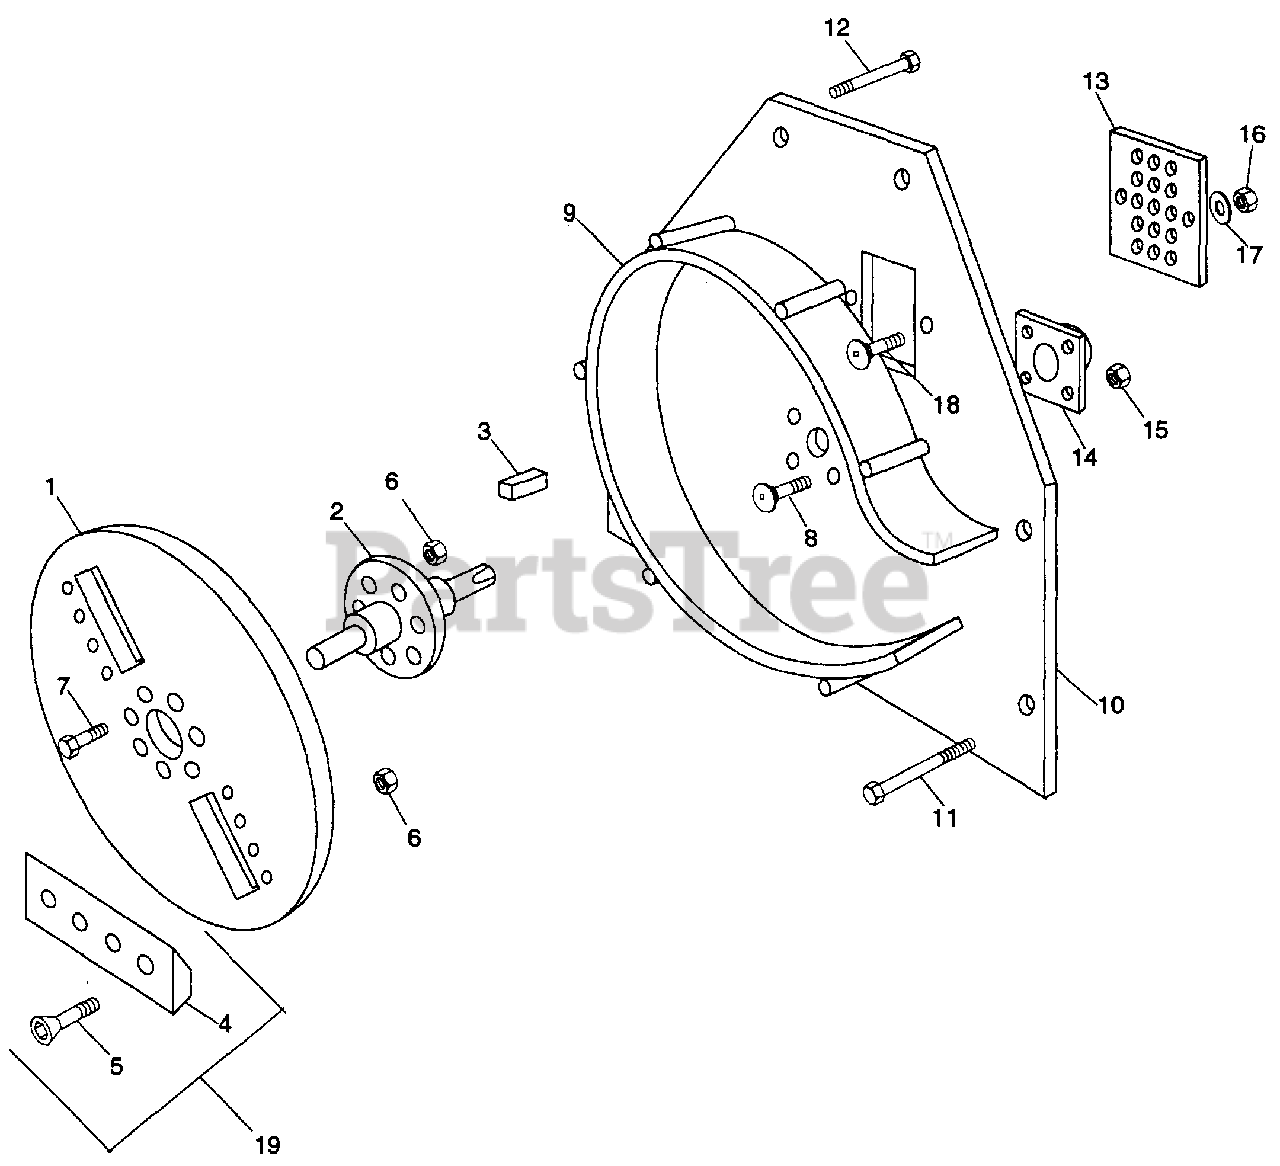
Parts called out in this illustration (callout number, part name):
1	CUTTING WHEEL
2	ARBOR SHAFT 210
3	KEY STR .38X2.0X.38
4	CUTTER BLADE
5	BLT-HEX .50-13X1.75 FL SKH
6	NUT-LK-CROWN .50-13 GR C PL
7	BLT-HEX .50-13X2.00 PL GR 5
8	BLT-LUG .50-20X1.50
9	DRUM STRAP WELDMENT
10	BLOWER SIDE L.H.
11	BLT-HEX .38-16X6.00 PL GR 5
12	BLT-HEX .38-16X5.50
13	INSPECTION PLATE
14	FOUR HOLE FLANGE BEARING
15	NUT-LK-TOP .50-20 GR C PL
16	NUT-HEX .375-16
17	WSHR-LOCK .375X.115 HVY PL
18	BLT-CARR SPLRIB .38-16X1.0 GR 5 PL
19	CHIPPER KNIFE KIT - 210/PTO
